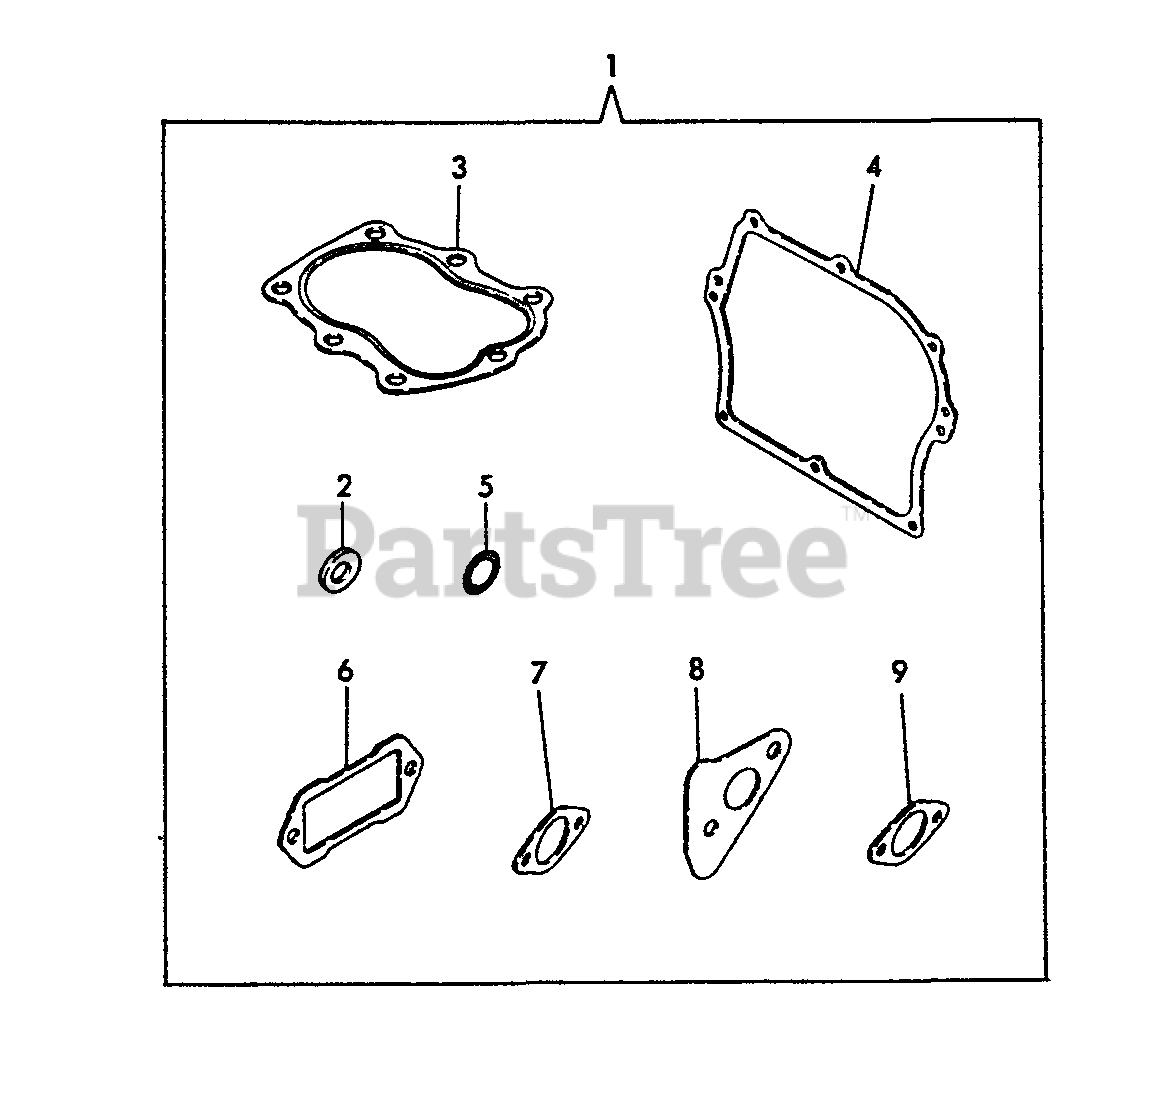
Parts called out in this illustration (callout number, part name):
1	GASKET KIT
2	GASKET
3	GASKET, CYLINDER
4	GASKET, SIDE COVER
5	O-RING - 18
6	GASKET, BREATHER
7	GASKET, INTAKE
8	GASKET, EXHAUST
9	GASKET, EXHAUST
